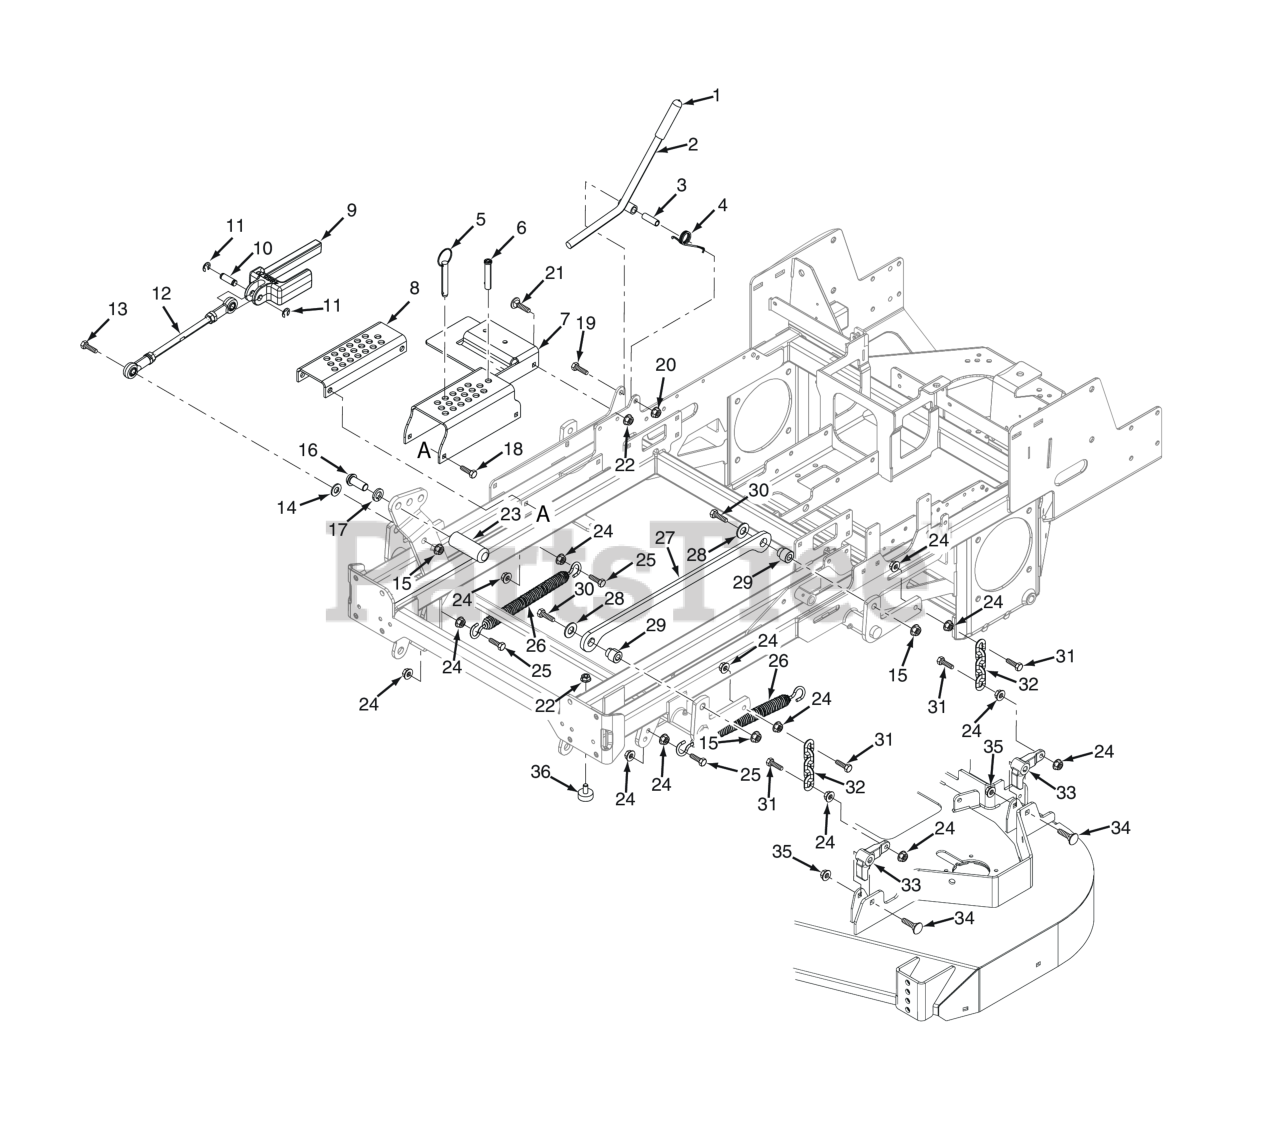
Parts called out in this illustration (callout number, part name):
1	Mounting Bracket, Fuel Tank
2	Deck Latch Assembly w/Grip
3	Bushing, .502 O.D.
4	Spring, Torsion - Lever Return
5	Lanyard, Deck Height Pin Assembly
6	Pin, Locking
7	Adjustment Bracket, Upper Cut Height
8	Adjustment Bracket, Lower Cut Height
9	Slide, Height Adjustment Assembly (INCL. 10,11,12)
10	Pin, Deck Lift
11	Retaining Ring, 1/2" Ext. "E"
12	Linkage, Deck Lift
12	Rod End, 1/2-20 Female RH Thread
12	Rod End, 1/2-20 Female LH Thread
12	Nut, 1/2-20 UNF-2B RH Thread
12	Bolt, Hex Hd. 5/16-18 x 3-3/4"
13	Hex Head Bolt, 1/2-13 x 2"
14	Flatwasher, 1/2 - .531 x 1.062 x .095
15	HEX LOCKNUT, ELASTIC STOP, 1/2-13
16	Capscrew, 5/8-11 x 1-1/2"
17	Lockwasher, 5/8" Spring
18	Bolt, Hex Wshr Head 5/16-18 x 1-1/4"
19	Capscrew, Hex Head 3/8-16 x 2.75"
20	HEX NUT, ELASTIC STOP LOCK, 3/8-16
21	Bolt, 5/16-18 x .75 RHSN Carriage
22	Nut, Serrated Flange 5/16-18 (Right Front Engine Mounting, Briggs and Kohler Only)
23	Foot Pedal, Height Adjustment
24	NUT, 3/8-16 SERRATED FLANGE HEX HEAD
25	Bolt, Hex Head 3/8-16 x 1-1/2" Grade 8 Black
26	Spring, Helper (61" & 72" Cutter Decks Only)
27	Link, Deck Lift
28	Flat Washer, 1/2 (.562 x 1.375 x .109)
29	Pivot, Deck Link
30	Bolt, Hex Head 1/2-13 x 2-1/4"
31	Bolt, Hex Head, 3/8-16 x 1-1/2"
32	Chain, Deck Lift
33	Lever, Deck Level
34	Bolt, Carriage 7/16-14 x 2-1/4"
35	HEX LOCKNUT, ELASTIC STOP, 7/16-14
36	Bumper, Rubber 5/16-18 x 5/8"
